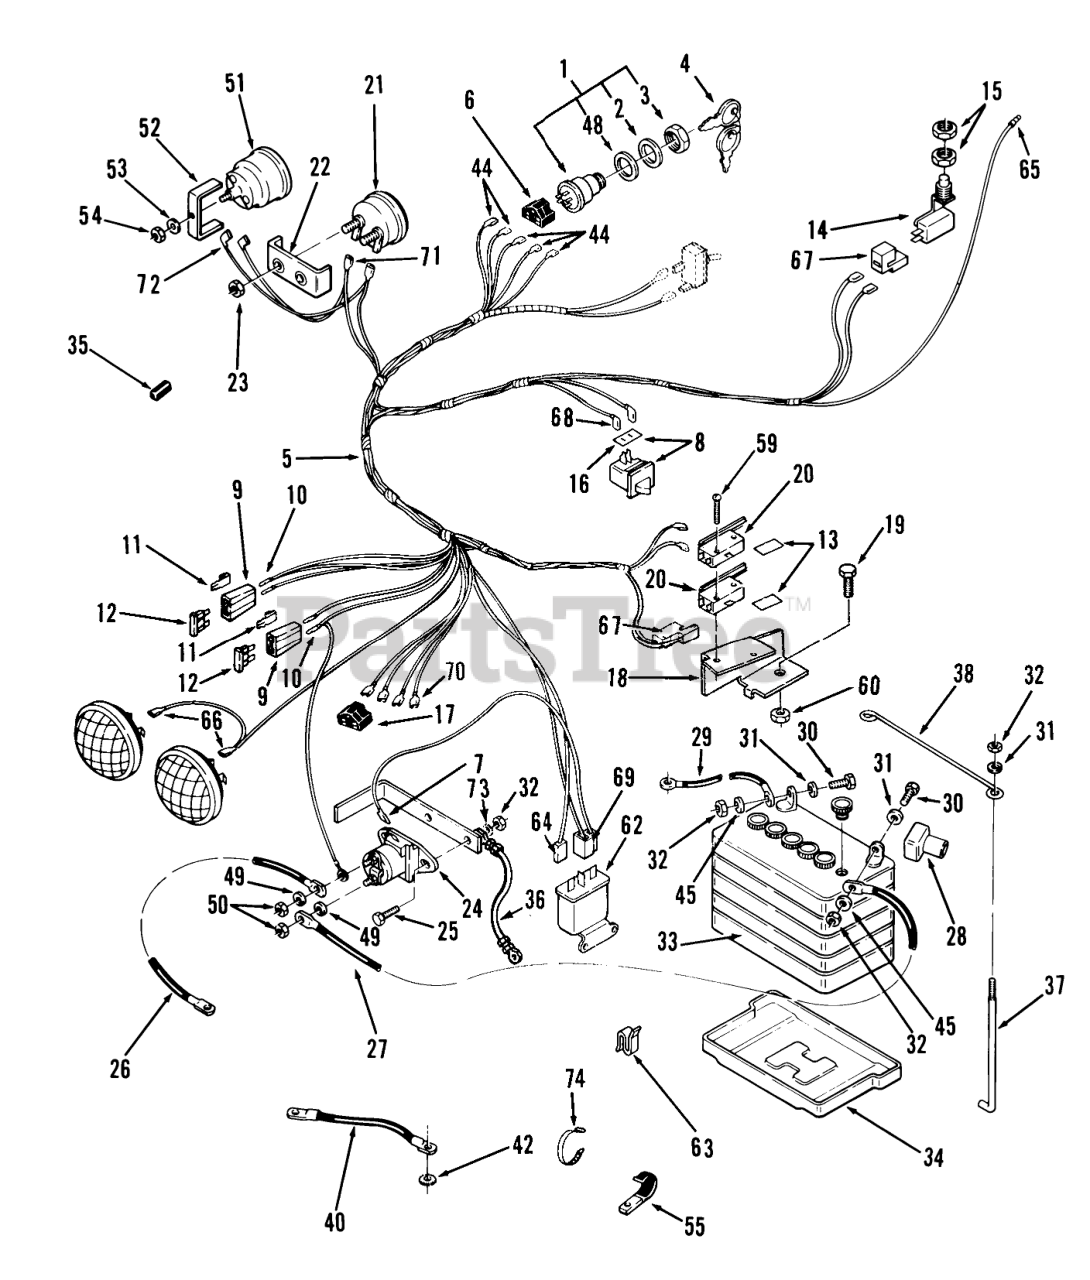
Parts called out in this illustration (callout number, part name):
1	Ignition Switch Ass-y
2	LOCKWASHER
4	Ignition Key
5	WIRING HARNESS
6	CONNECTOR-5 WAY-SERV
7	TERMINAL 10
8	SWITCH ASM (SERVICE)
9	AUTO-FUSEBLOCK TERM
10	TERMINAL FUSE
12	FUSE-BLADE, 5 AMP
13	BARRIER - SWITCH
14	Seat Switch
15	NUT-HEX, SPECIAL
16	SHIELD-DIRT SPST
17	5-CONTACT CONN BODY
18	Support-Switch
19	Bolt
20	SWITCH
21	Voltmeter (w/109650)
22	CLAMP MOUNTING
23	HEX NUT 10-32 E.S.
24	SOLENOID-STARTER
25	Screw
26	ASSY WIRE
27	CABLE-BLACK
28	Boot
29	ASSY WIRE
30	Bolt
32	Nut
33	Battery Maintenance Free 416
34	TRAY BATTERY
35	GRIP
36	GROUND-WIRE
38	HOLDDOWN-BATTERY
40	WIRE GROUND
42	Washer-Lock
44	Terminal
45	Washer
48	Washer
49	Washer
50	Nut
51	Hourmeter 314, 417
52	HOUR METER CLAMP
53	Lockwasher
54	Hex Nut
55	CLIP
59	Screw
60	NUT HEX 4-40 ELAST
62	Relay
63	CLIP-CABLE
64	TERMINAL 10
65	Sur-Plug
67	CONNECTOR BODY
68	Terminal
69	CONNECTOR BODY B
70	Connector Part of 5
71	TERMINAL-TAB RCPT
72	Terminal Part of 5
73	LOCKWASHER
74	PLASTIC TIE
